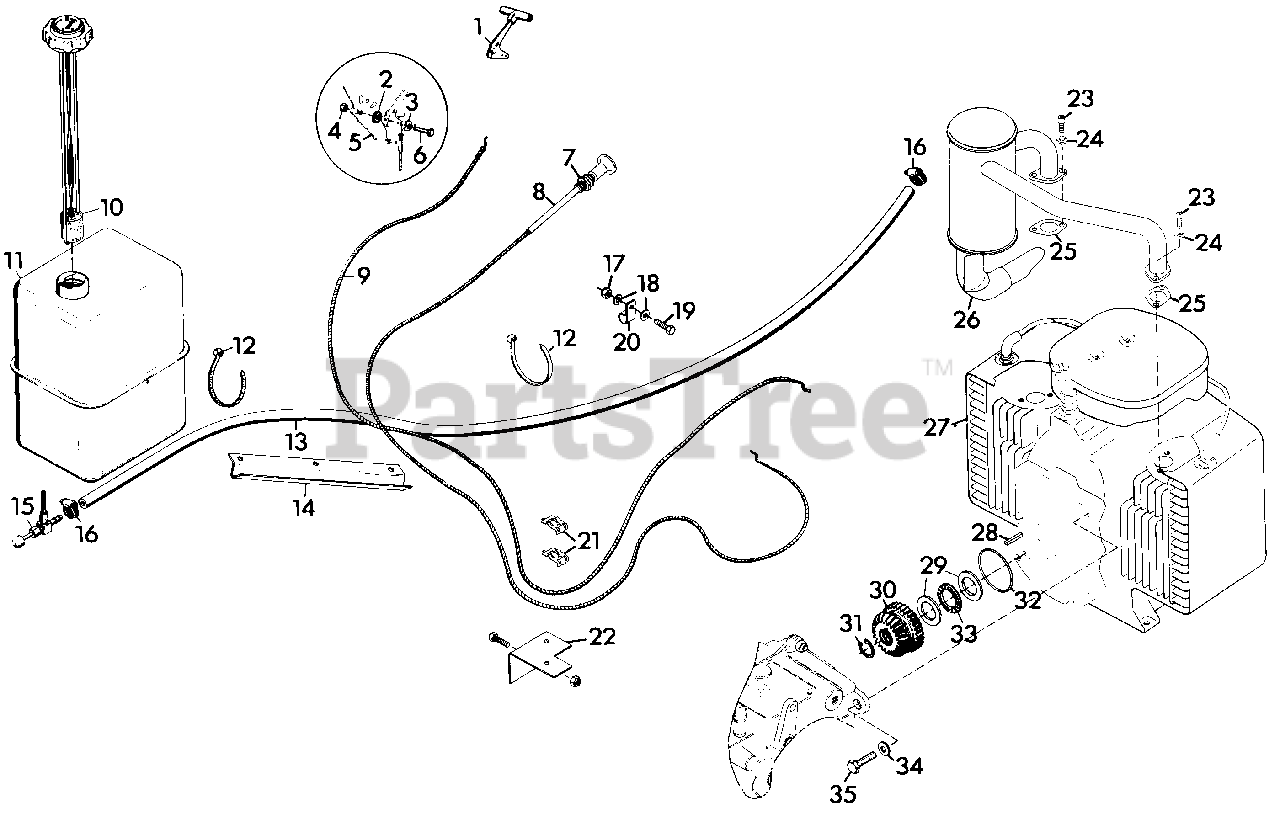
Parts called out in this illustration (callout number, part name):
1	ASSEMBLY, KNOB AND LEVER
2	WASHER, FRICTION
3	WASHER, SPRING
4	NUT, LOCK 1/4-28
5	BRACKET, MOUNTING
6	BOLT, HEX 1/4-28X.75
7	NUT, JAM 3/8-24 HEX
8	CONTROL, CHOKE
9	ASSEMBLY, CHOKE CONDUIT
10	GAUGE, GAS
11	TANK, FUEL
12	TIE, CABLE
13	LINE, FUEL
14	SHIELD, HEAT
15	VALVE, FUEL 90 DEG. REVERSE FLOW
16	CLAMP, HOSE
17	NUT, LOCK 5/16-18
18	WASHER, FLAT .343X.688X.065
19	BOLT, HEX 5/16-18X1.00
20	CLAMP, NYLON
21	CLIP, SPEED
22	BRACKET, THROTTLE AND CHOKE
23	SCREW, CAP 5/16-18X.75 SOCKET HD
24	WASHER, LOCK 5/16 REG.
25	GASKET, EXHAUST
26	MUFFLER, EXHAUST
27	ENGINE, 18 H.P.
27	ENGINE, 20 H.P.
28	KEY, SQUARE .250X1.250
29	RACE, BEARING THRUST 1.125X1.750X.123/.126
30	GEAR, SPUR AND BEVEL, INPUT
31	RING, RETAINING 1.125 SHAFT
32	O-RING, 3.000X3.188X.094
33	BEARING, THRUST 1.127X1.740X.078
34	WASHER, LOCK 1/2 REG.
35	BOLT, HEX 1/2-13X1.75
NS	NUT, LOCK 10-32
NS	SCREW, MACHINE 10-32X.50 PHD
